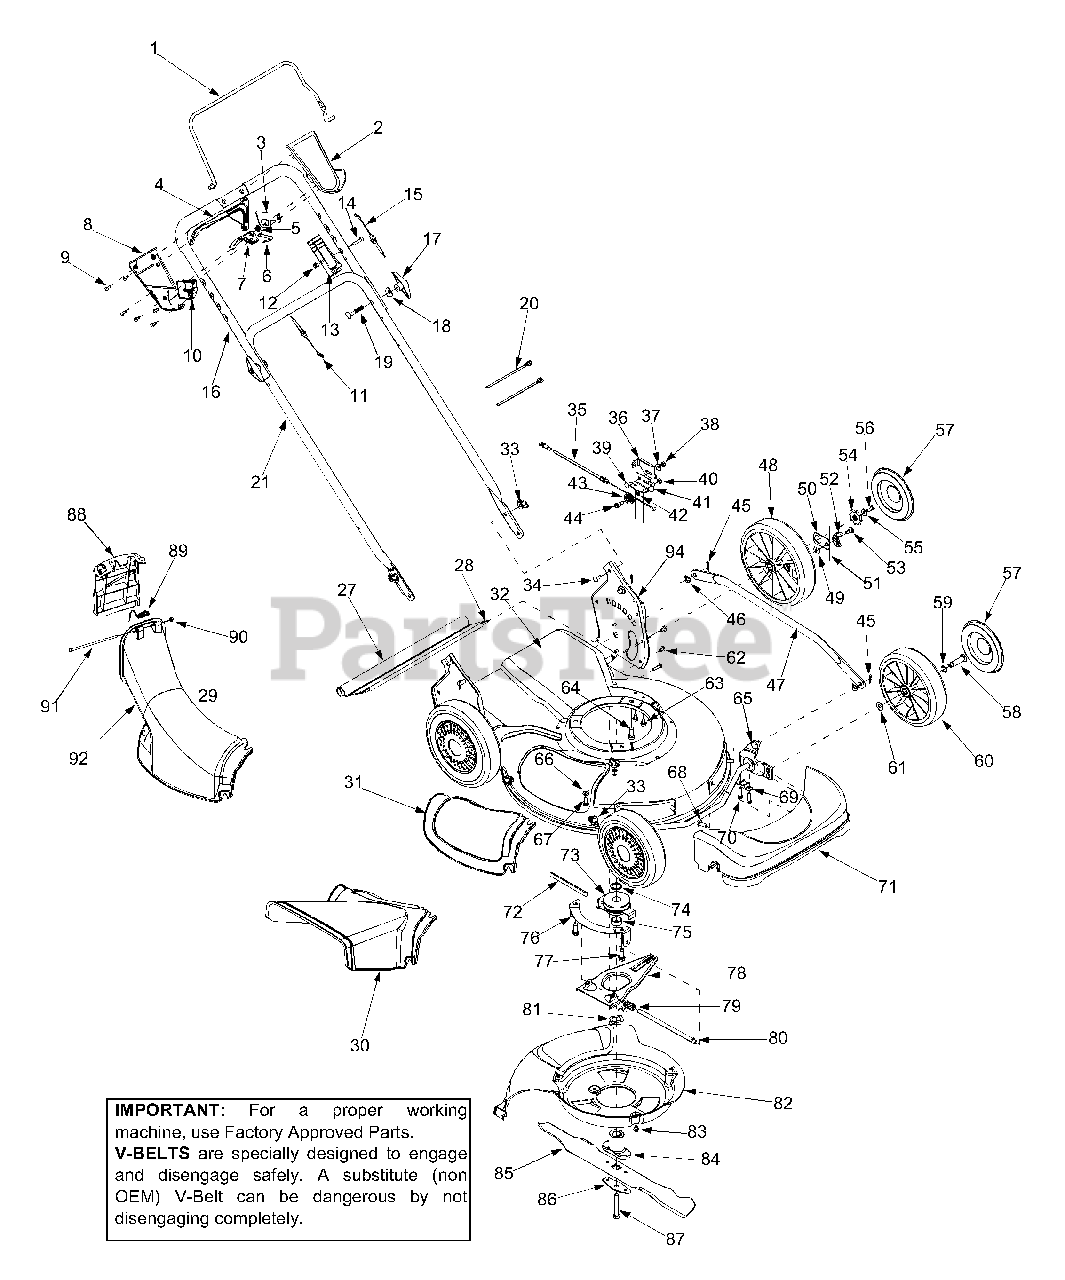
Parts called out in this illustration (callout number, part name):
1	Control Handle
2	Upper Control Housing
3	6 Speed Rack Cable Bracket
4	Control Lever
5	Gear Insert
6	Shift Lever Spring
7	6 Speed Shift Lever
8	Lower Control Housing
9	C Sunk Tap Screw #10 x.75 Lg
10	Cable Mounting Cap
11	Drive Cable 51.0
12	Top Lock Nut 1/4-20
13	Control Housing
14	Oval C-Sunk Screw
15	Control Cable (Briggs & Stratton)
17	Wing Nut
18	Saddle Washer.320 ID x.830 OD
19	Carriage Bolt 5/16-18 x 2.0
20	Cable Tie
27	Trail Shield
28	Trail Shield Wire
29	Chute Assembly
30	Side Discharge Chute
31	Mulch Cover
33	Wing Nut
34	Carriage Bolt 1/4-20 x.75
35	6 Speed Cable
38	Hex Nut 1/4-20
39	Carriage Screw 1/4-20 x.50
40	Hex Nut 1/4-28
43	Roller Cable
44	Shoulder Screw.375 ID x 1/4-14
45	Cotter Pin
46	Bowed Washer
48	Wheel 9 x 2.125
49	Top Lock Tab Weld Nut 1/4-20
50	Ratchet Pawl Plate
51	Plastic Spring Ratchet
52	Pawl RH
53	Shld Screw.340 ID x.285 OD
54	Wheel Rachet
55	Bell Washer.265 ID x.75 OD
56	Hex Cap Screw 1/4-20 x.620
57	Hubcap
58	Shoulder Screw.498 x 1.445
59	Wave Washer.510 ID x.750 OD
60	Wheel 8 x 2.125
61	Spring Washer.401 ID x.870 OD
62	Screw 1/4-14 x.500
63	Screw 1/4-14 x.625
64	Hex Washer Screw 3/8-16 x 1.0
66	Flat Washer.344 ID x.62 OD
67	Carriage Screw 1/4-20 x.75
68	Torx Screw
69	Block Bushing
70	Hex Washer Screw
71	Front Axle Cover
72	Belt 3/8 x 39.24
73	Pulley Assembly
74	Sleeve Spacer.88 ID x 1.13 OD
75	Sleeve Spacer.88 ID x 1.00 OD
77	Screw 3/8-18 x 1.0
80	Pivot Shaft
81	Wave Washer 1.38 ID x.88 OD
82	Baffle
83	Screw 1/4-20 x 3.75
84	Blade Adapter Kit
85	21" Mulching Blade
86	Blade Bell Support
87	Hex Bolt 3/8-24 x 2.5
88	Chute Door
89	Torsion Spring
90	Push Cap
91	Pivot Rod
92	Discharge Chute
